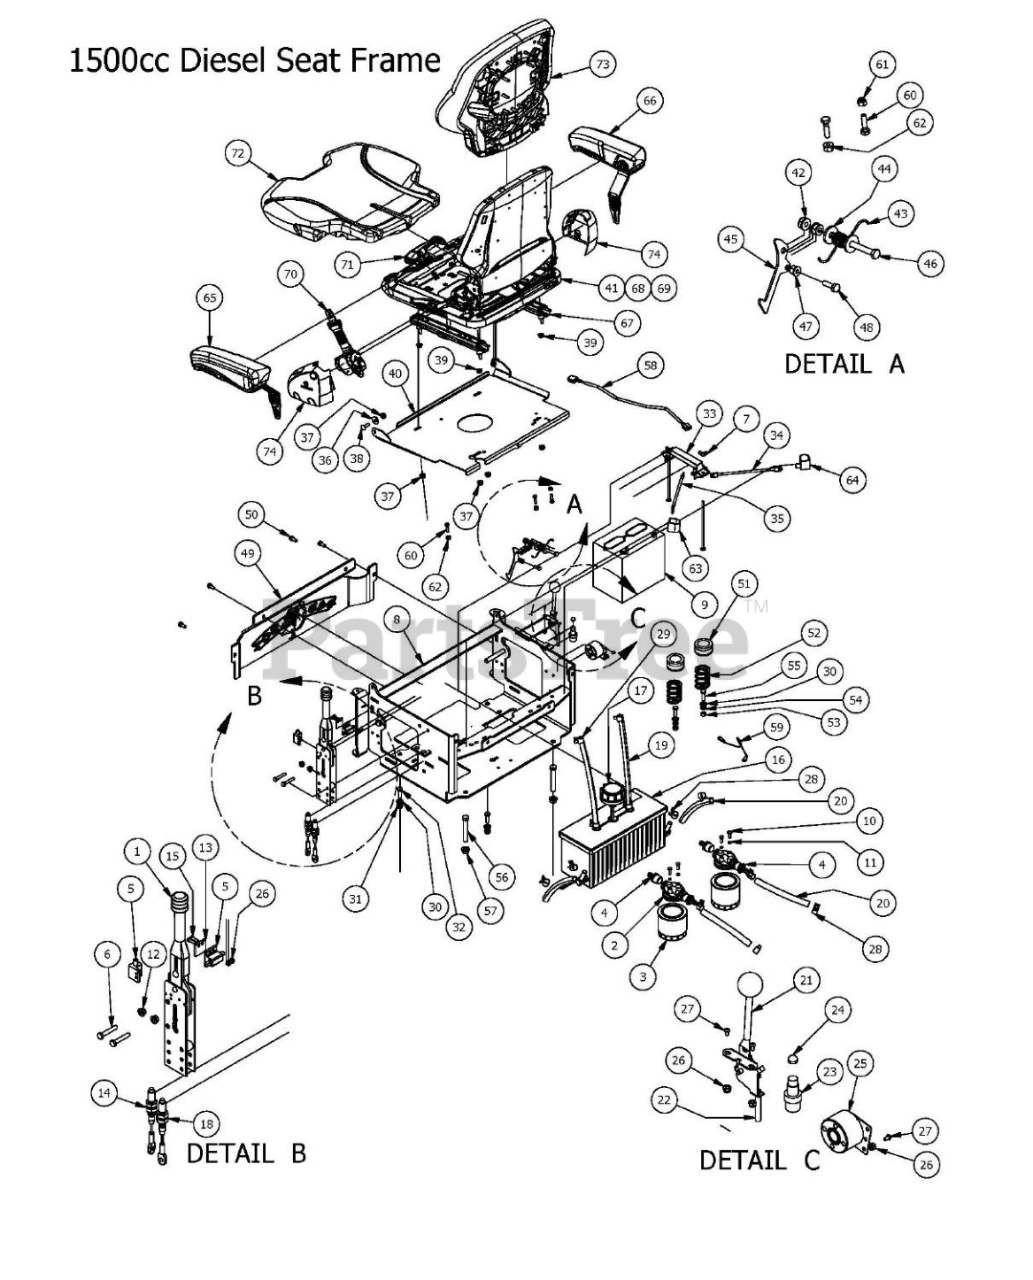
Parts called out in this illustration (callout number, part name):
1	Hand Brake Assembly
2	Filter Head
3	Hydraulic filter
4	Filter Head Fitting
6	5/16" x 1 3/4" Hex Bolt
7	1/4" Wing Nut
8	2007 Diesel Seat Frame
9	Battery Diesel Models -151
10	1/4" x 3/4" Hex Bolt
11	1/4" Lock Washer
12	5/16" Flange Nut w/Serrations
13	Switch Block Plastic
14	Short Brake Cable
15	1024 x 1" Allenhead Bolt
16	Aluminum Hydraulic Tank
17	Hydraulic Tank Cap
18	Long Brake Cable
19	3/8" x 32" Clear Hose
20	1/2" x 9 1/4" Braided Hose
21	Throttle - Diesel
22	Diesel Throttle Cable Only
23	Momentary Start Switch
24	Start Switch Boot - Diesel
25	Heat Warning Piezo Buzzer
26	#10 Nylock Nut
27	1024 X 5/8" Buttonhead Bolt
28	1/2 Hose Clamp
29	3/8 hose clamp
30	3/8" Flat Washer
31	3/8" Flange Nut
32	3/8" x 1 1/4" Hex Bolt
33	Battery Hold Down
34	Black Battery Cable - Diesel
35	Red Battery Cable - Diesel
36	.360 ID Plastic Washer
37	5/16-18 Nylon Flange Nut
38	5/16" x 1" Carriage Bolt
39	5/16" Flange Nut
40	Seat Plate
41	Grammer Seat With Seatbelt
42	5/16-18 Nylon Flange Nut
43	Torsion Spring for Seat latch
44	.360 ID Plastic Washer
45	Seat Latch Lever
46	5/16-18 X 2 Hex C/S (GR.5) ZC
47	1/4-20 Nylon Insert flange Nut
48	1/4-20 x 1-1/4 GR 5 Hex Bolt
49	Cooler Cover
50	5/16 x 3/4 washer head type F screw
51	Seat Spring Cap Cover
52	Seat Spring
53	3/8" Hex Nut
54	3/8" Lock Washer
55	3/8" x 1 1/2" Hex Bolt
56	1/2 x 3 1/2 Flange Bolt Grade 8
57	1/2" Flange Nut
58	Seat Switch Adapter
59	Seat Cable
60	1/4-20 x 1 GR 5 hex bolt zinc
61	1/4 Nylock Nut
62	1/4-20 Nylon Insert flange Nut
64	Black Boot For Ground Cable
65	Left Armrest Kit for Grammer Seat
66	Right Armrest Kit for Grammer Seat
67	Rails for Grammer Seat (Pair)
68	Grammer Seat (No Seat Belt)
69	Grammer Seat (Black and Orange)
70	Seat Belt Kit for Grammer Seat
71	Grey Handle Assembly
72	Seat Cushion for Grammer Seat
73	Back Cushion for Grammer Seat
74	Plastic Side Covers for Grammer Seat
75	Grammer Seat Safety Switch (Not
